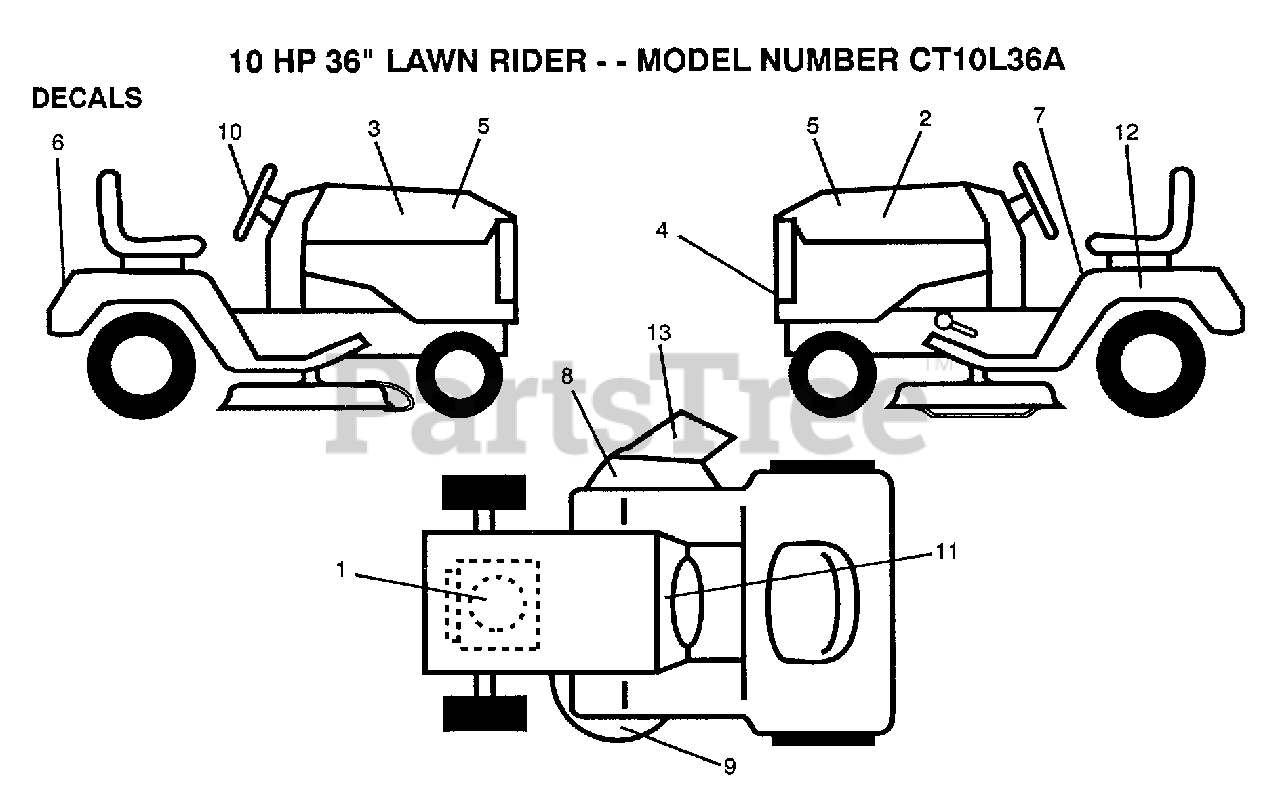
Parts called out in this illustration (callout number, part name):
1	DECAL.B&S.272129
2	"DECAL,STP HD LH"
3	"DECAL,STP HD RH"
6	"DECAL,FENDER"
7	DECAL
8	DECAL WARING
9	DECAL INSTRUCTION CAUTION
10	"DECAL,STR WHL"
12	DECAL
13	DECAL WARNING
